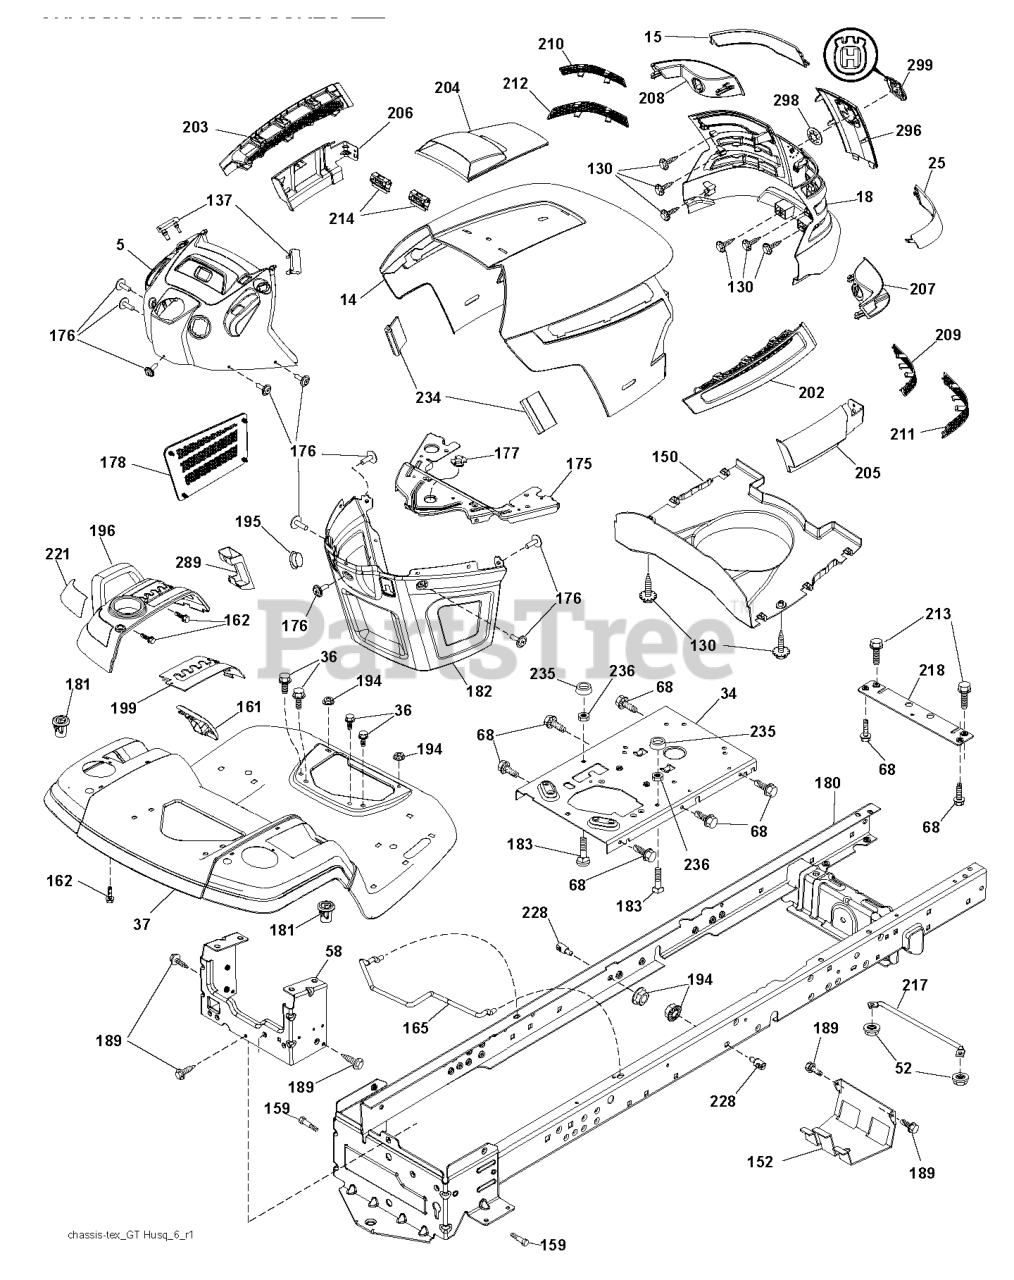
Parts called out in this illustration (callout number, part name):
5	DASH.ASM.HUSQ.GT.E.RECT.W/CK
14	HOOD
15	LENS.LH.TEX.GT.HUSQ.CL
18	GRILL.ASM.HUSQ.TG/CRD.W/TRIM
25	LENS.RH.TEX.GT.HUSQ.CL
34	PLATE.ENGINE.WELDED.CHASSIS
36	SCREW 5/16"
37	FENDER.PNT.TX.GT.CH/FW.ORANGE
52	LOCKNUT
68	Screw 5/16-18 x 1/2 Hex, Self Tapping 5/16-18 x 1/2
130	SCREW.#10 X 0.750.BOS
137	BUMPER DASH
150	AIR.DUCT.TEXGT.HUSQ.31
152	SHIELD.BROWNING.W/TEX
159	SCREW, 3/8-16X3/4
161	CONSOLE.FUEL.WINDOW.HU
162	SCREW.HI-LO.CONSOLE
165	SUPPORT.TANK.REAR.W/TEX
175	PLATE.CROSSMEMBER.HUSQ
176	SCREW.#10-24X5/8.RN.QU
177	BUSHING, STEERING
178	CARGO.ASM.NET.TXGT.W/C
180	CHASS.WLDMNT.TLT.12GA/2PC.20"
181	BUSHING.MNT.FEND.CRGO.
182	DASH.LOWER.COMMON.12V.ADAPTOR
183	BOLT.5/16-18X1-1/4 FULL.THREAD
189	SCREW
194	NUT LOCK HEX FLANGE 5/16-18
195	PLUG.HOLE.DASH.LOWER.12V.BLK
196	RP CONSOLE.ASM.DECKLFT.W/
199	PLATE.DECK.LIFT.HUSQVARNA.GT
202	VENT.SIDE.HOOD.HUSQ.RH.GREY
203	VENT.SIDE.HOOD.HUSQ.LH.GRAY
204	HOOD VENT
205	SKIRT.HOOD.SIDE.HUSQ.RH.GREY
206	SKIRT.HOOD.SIDE.HUSQ.LH.GREY
207	BEZEL.RH.TEX.GT.HUSQ
208	BEZEL.LH.TEX.GT.HUSQ
209	INSERT.HEX.GRILL.HUSQ.GREY
210	INSERT.HEX.GRILL.HUSQ.
211	INSERT.HEX.GRILL.HUSQ.
212	INSERT.HEX.GRILL.HUSQ.
213	BOLT
214	CLIP.RETAINER.TINNER.
217	ROD.PIVOT.HOOD
218	X-PIECE.HOOD.STOP.NON/
221	REFLECTOR.LH.TEX GT HU
228	STUD.FASTNER.W/ANTI-ROTATE
234	BUMPER.HOOD.TEX.HUSQVARNA
235	SPACER FENDER
236	NUT.CENTERLOCK.5/16-
289	PLUG.N/CRUISE.COMMON.YT/GT.BLK
296	TRIM.HUSQ.TG/CRD.SERVICE
298	NUT PUSH M
299	RP LOGO
